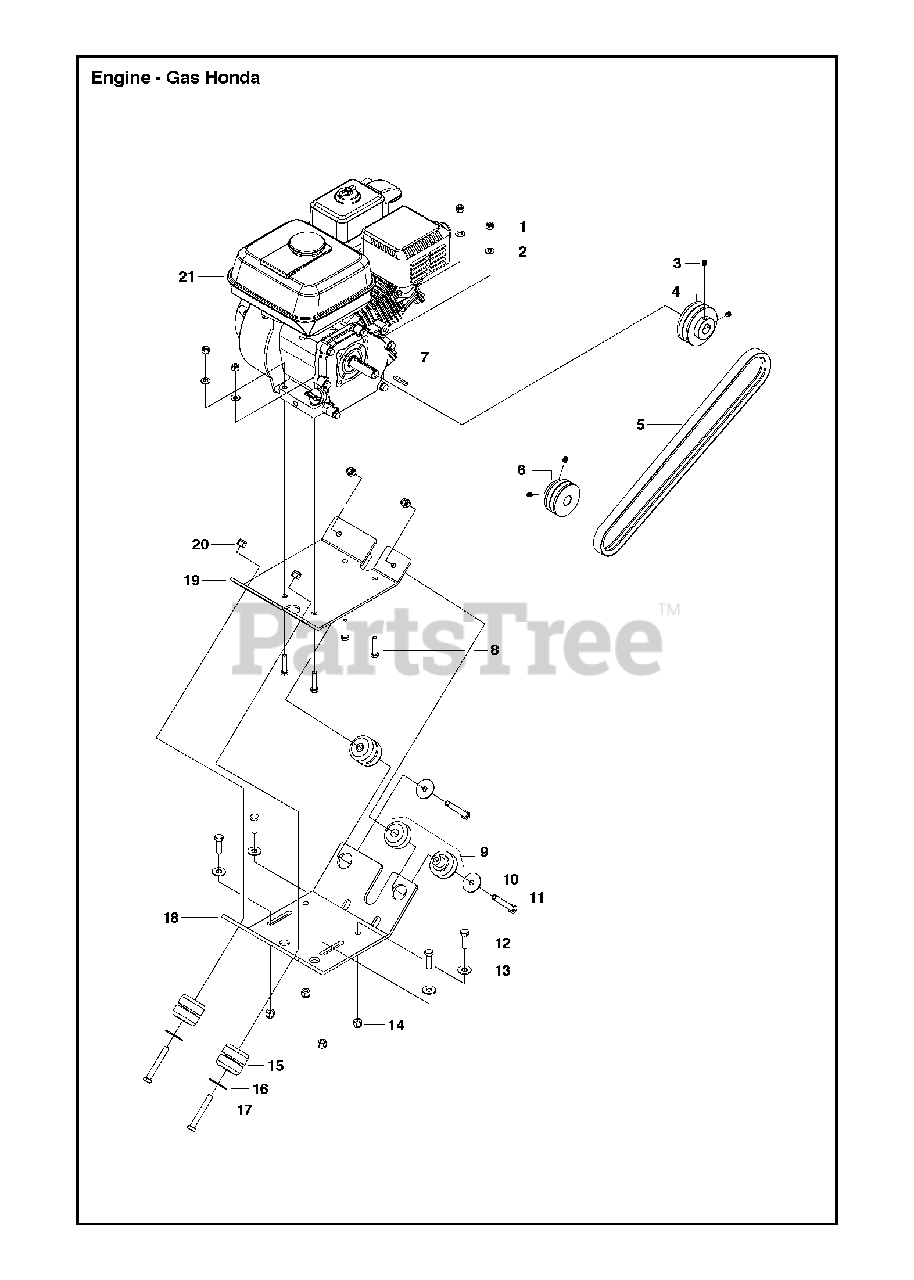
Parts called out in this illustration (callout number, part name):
2	WASHER
5	V-BELT: 2/3VX425 - 2 BELT BAND
14	NUT
20	NUT
